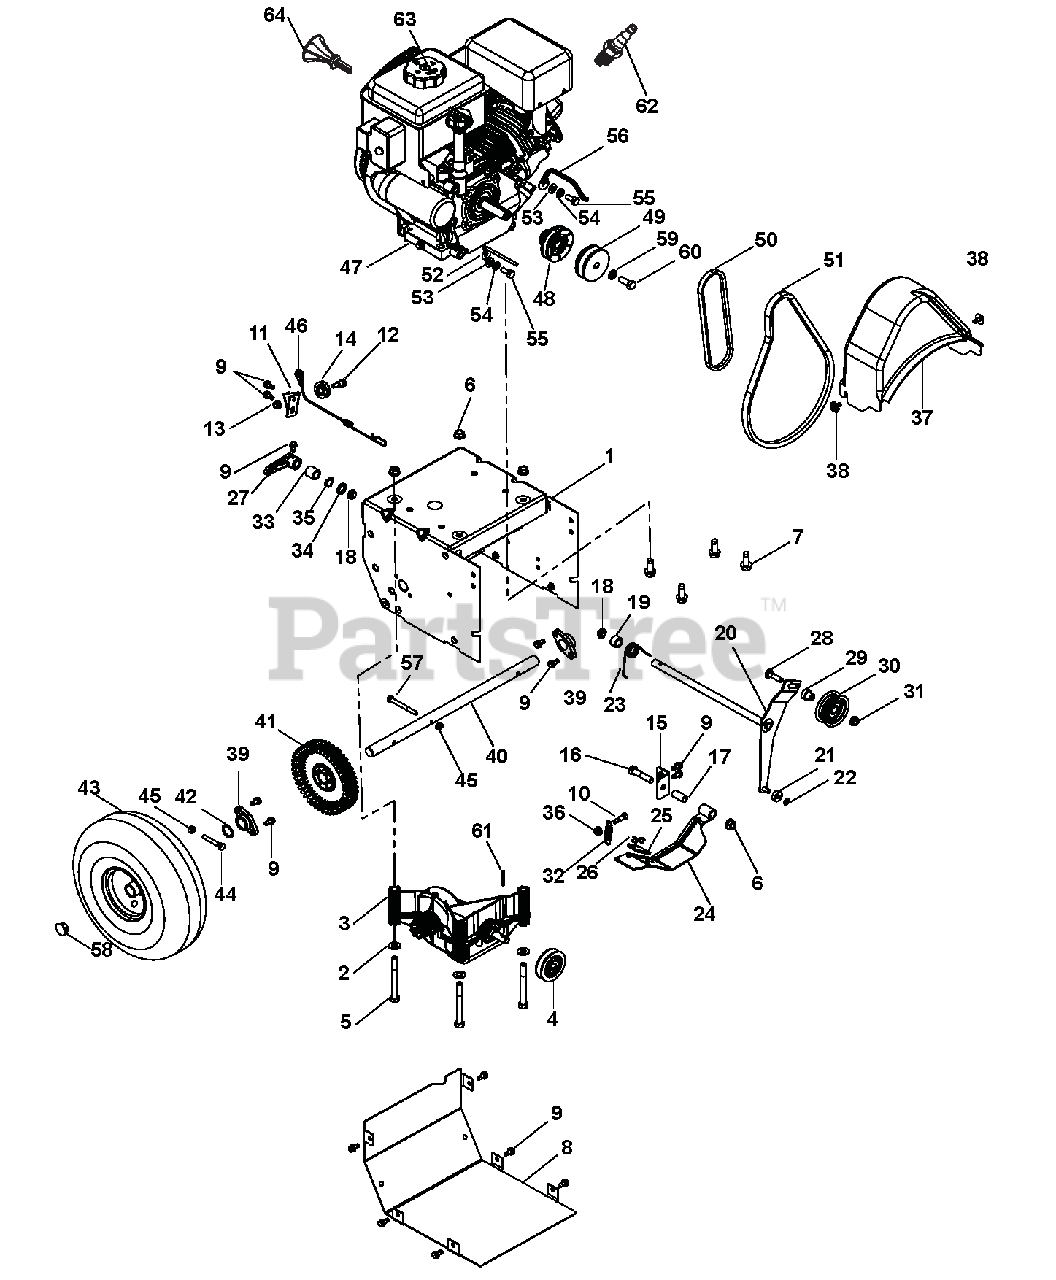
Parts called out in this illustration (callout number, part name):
1	FRAME, WELDMENT
2	@WSHR-FL-STL.406X.812X.065 YWZ
3	TRANSMISSION, GT H0 W/O PULLEY
4	PULLEY, COMPOSITE 3L (2.308)
5	@BLT-HEX .38-16X3.50 GR5 YWZC
6	@NUT-LK-TOP-FLG .38-16 YWZC
7	SCR-TAP .38-16X1.0 HWH YZ W/VT
8	COVER, BOTTOM
9	SCR-TAP .25-20X.50 HWH TR YWZ
10	BLT-SHLDR .31X.50 .25-20X.438
11	BRACKET, CABLE PULLEY
12	BOLT, SHLDR-.375X.375X.25-20
13	@NUT-LK-TOP-FLG .25-20 YWZC
14	PULLEY, CABLE
15	BRACKET, MOUNT - BRAKE
16	@BLT-HEX .38-16X1.75 GR5 YWZC
17	BSHG-SLV .385X.500X1.045
18	BUSHING, POLYLINER-.50 SNAPIN
19	BSHG-SLV .510X.751X.475
20	WELDMENT, ATTACHMENT IDLER ARM
21	BSHG,SLV .270 X .750 X .250
22	RG-RTNG-EXT .250X.010
23	SG-TORS .067X.88
24	BRAKE ARM W/PAD
25	PAD, BRAKE
26	RVT-POP .187 YZ
27	ARM, CLUTCH - ATTACHMENT
28	@BLT-RHDSHSQNK.31-18X1.25 G5YZ
29	SPCR, BRG .315X.50X.688X.281
30	IDLER
31	@NUT-LK-TOP-FLG .31-18 YWZC
32	SG-TENS .06X.46X2.00
33	BSHG-SLV .510X.751X.750
34	WSHR-FL-STL .52X.827X.062 YWZC
35	WSHR-WAVE .50X.75X.015 .13FRHT
36	@NUT-SPNLK-FLG .25-20 YWZC
37	COVER, BELT
38	SCR-TAP .25-20X.50 LGHWH TR YZ
39	BSHG .75X1.125X.65
40	SHAFT, AXLE - SINGLE SPEED
41	GEAR, AXLE 45T POLYMER
42	WSHR-FL-STL .754X1.000X.032 YZ
43	TIRE/WHEEL, 4.10-4
44	BLT-HEX .25-20X1.75 GR8 YWZC
45	@NUT-LK-CTR .25-20 YWZC
46	CABLE, LOWER TRACTION,SS & PRO
47	ENGINE,LCT STORMFORCE 208 120V
48	SHEAVE, DRIVE
49	SHEAVE, ENGINE
50	V-BELT, 3L-STRETCH FIT
51	V-BELT, 4L-RAW EDGE
52	BELT FINGER
53	@WSHR-FL-STL.344X.688X.065YWZC
54	WSHR-LK .312X.097 HVY YWZC
55	BLT-HEX .31-24X.75 YWZC GR5
56	FINGER, BELT
57	@BLT-HEX .25-20X2.5 GR8 YWZC
58	PLUG, HOLE - 0.75"
59	@WSHR-LK .38X.094 REG YWZC
60	BLT-HEX .38-24X1.0 YWZC GR5
61	PIN-ROLL, 5MMX26MM
62	PLUG, SPARK
63	CAP, FUEL TANK BLACK
64	KEY, PUSH/PULL LCT (2/PACKAGE)
